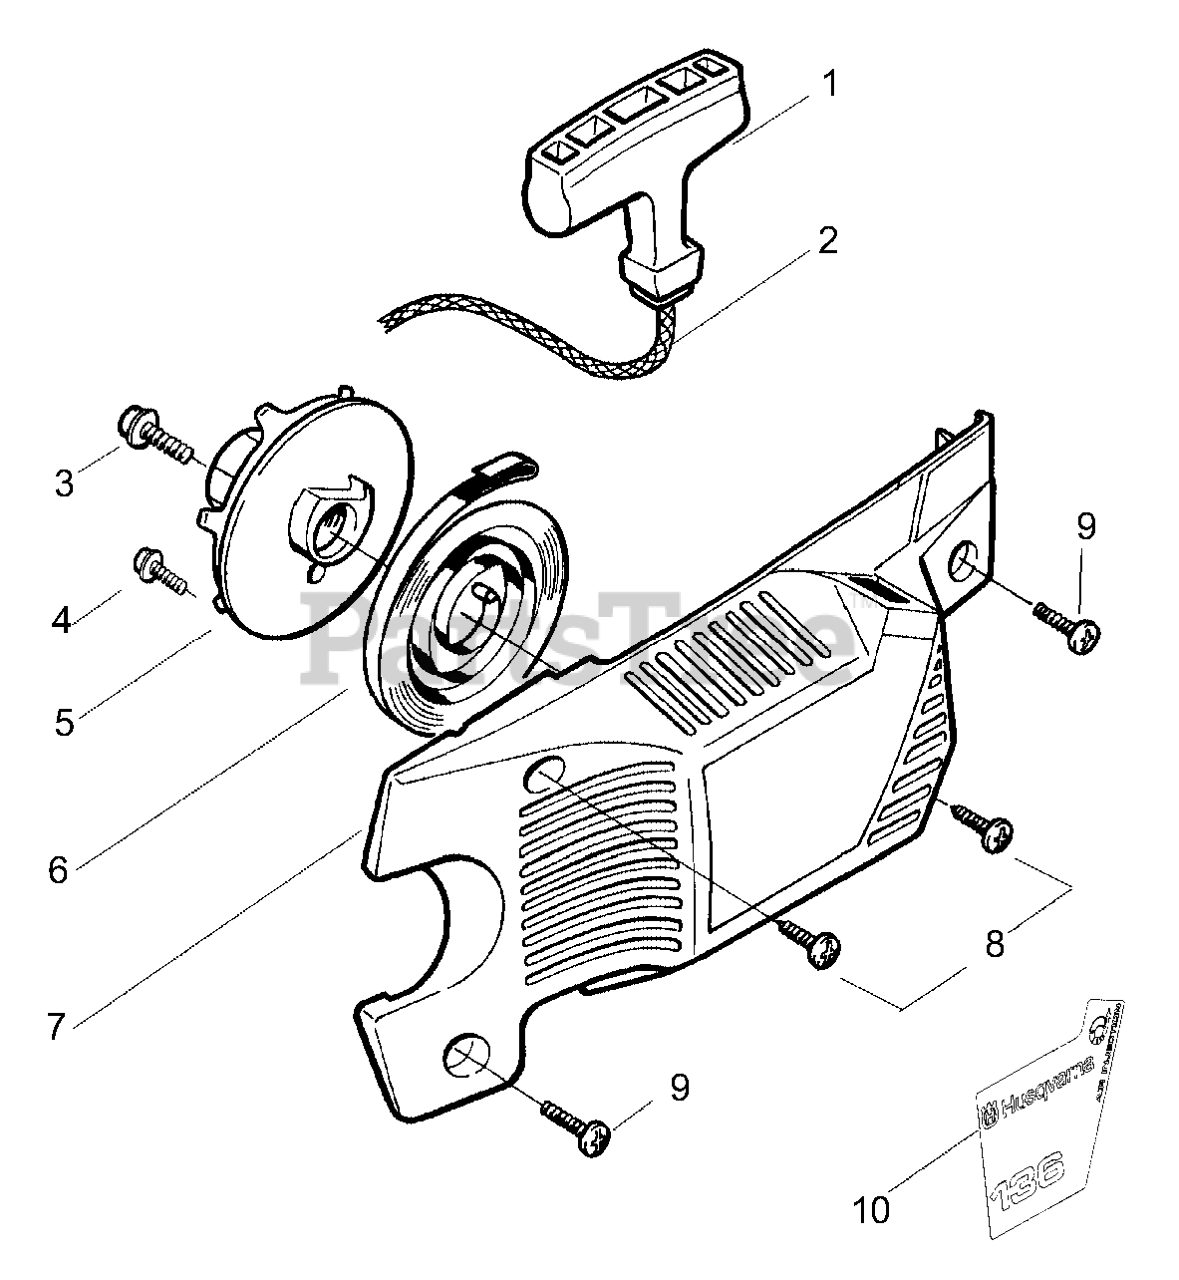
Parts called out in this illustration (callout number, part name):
1	STARTER HANDLE
5	PULLEY 36/41
6	RECOIL SPRING
7	FAN HOUSING ASSEMBLY
8	SCREW,STRTR CVR 36/41
